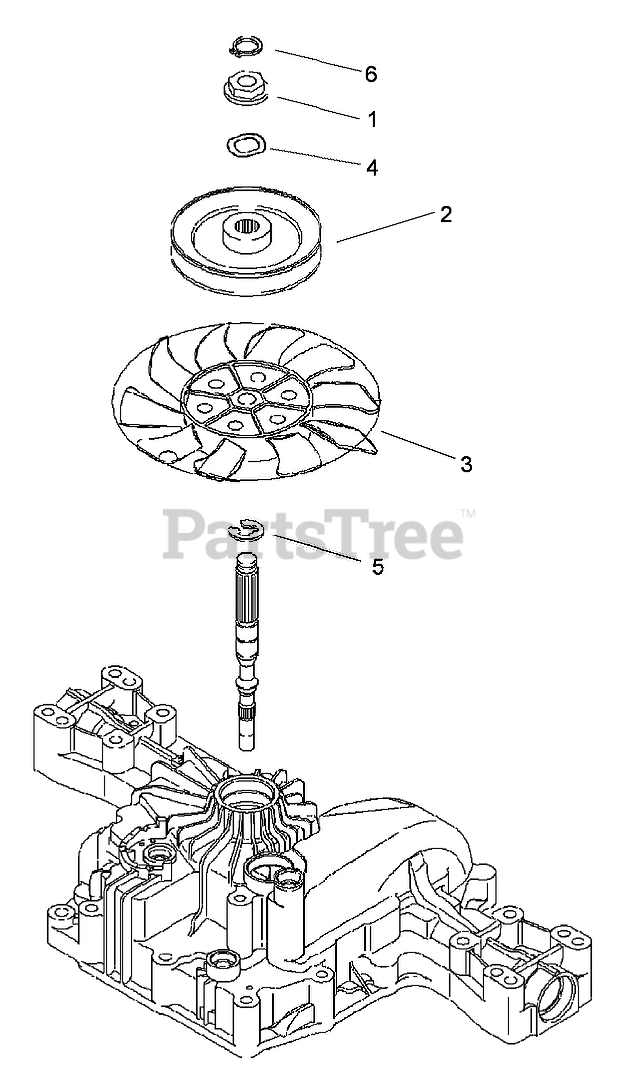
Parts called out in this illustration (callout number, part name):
1	Collar-Spline
2	PULLEY-TRANSMISSION
3	FAN-TRANSMISSION
4	Washer-Lock
5	E-RING
6	E-RING
